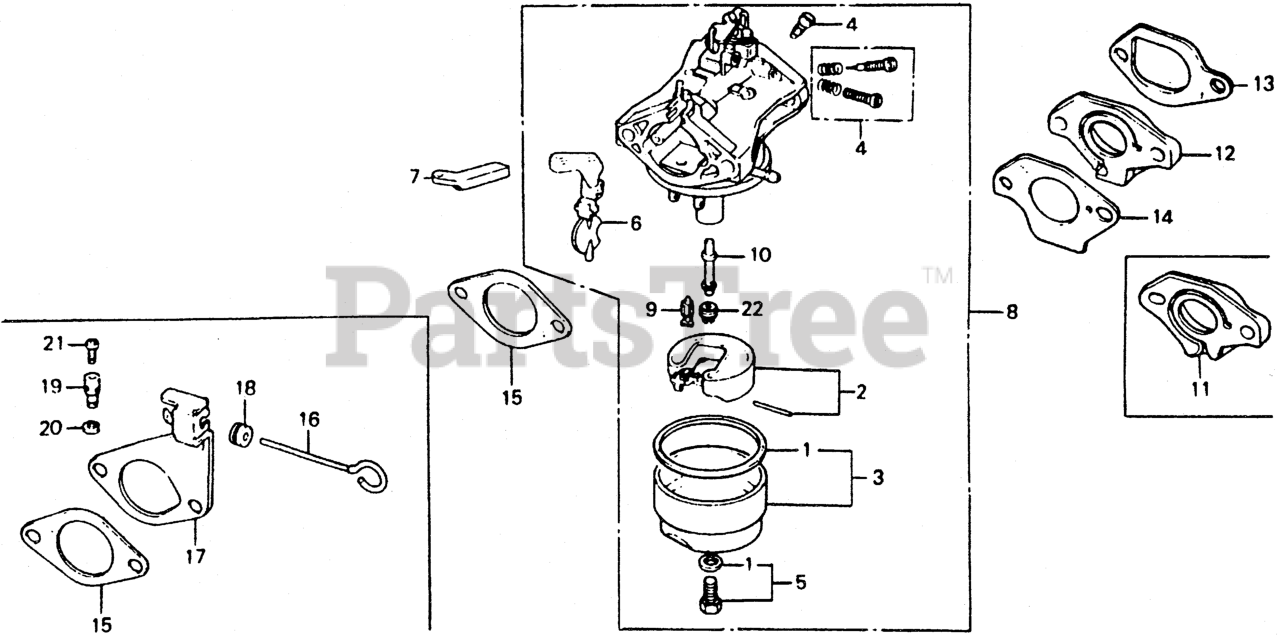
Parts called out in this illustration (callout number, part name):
1	GASKET SET
2	FLOAT SET
3	CHAMBER SET, FLOAT (CARBURETOR NO.) (NOT AVAILABLE)
4	SCREW SET A
5	SCREW SET B
5	SCREW SET
6	CHOKE SET
8	CARBURETOR ASSY. (BB33C A/B) (NOT AVAILABLE)
8	CARBURETOR ASSY. (BB33C C) (NOT AVAILABLE)
9	VALVE, FLOAT
10	NOZZLE, MAIN
12	INSULATOR, CARBURETOR
13	GASKET, INSULATOR
14	GASKET, CARBURETOR
15	GASKET, AIR CLEANER
16	ROD, CHOKE CONTROL
17	STAY, CHOKE CONTROL
18	GROMMET, CHOKE ROD
19	HOLDER, CABLE
20	CIRCLIP (5MM) Use from Engine SN 2327377.
21	SCREW, PAN (4X8)
22	JET, MAIN (#75)
22	JET, MAIN (#78)
22	JET, MAIN (#80)
22	JET, MAIN (#82)
22	JET, MAIN (#85)
